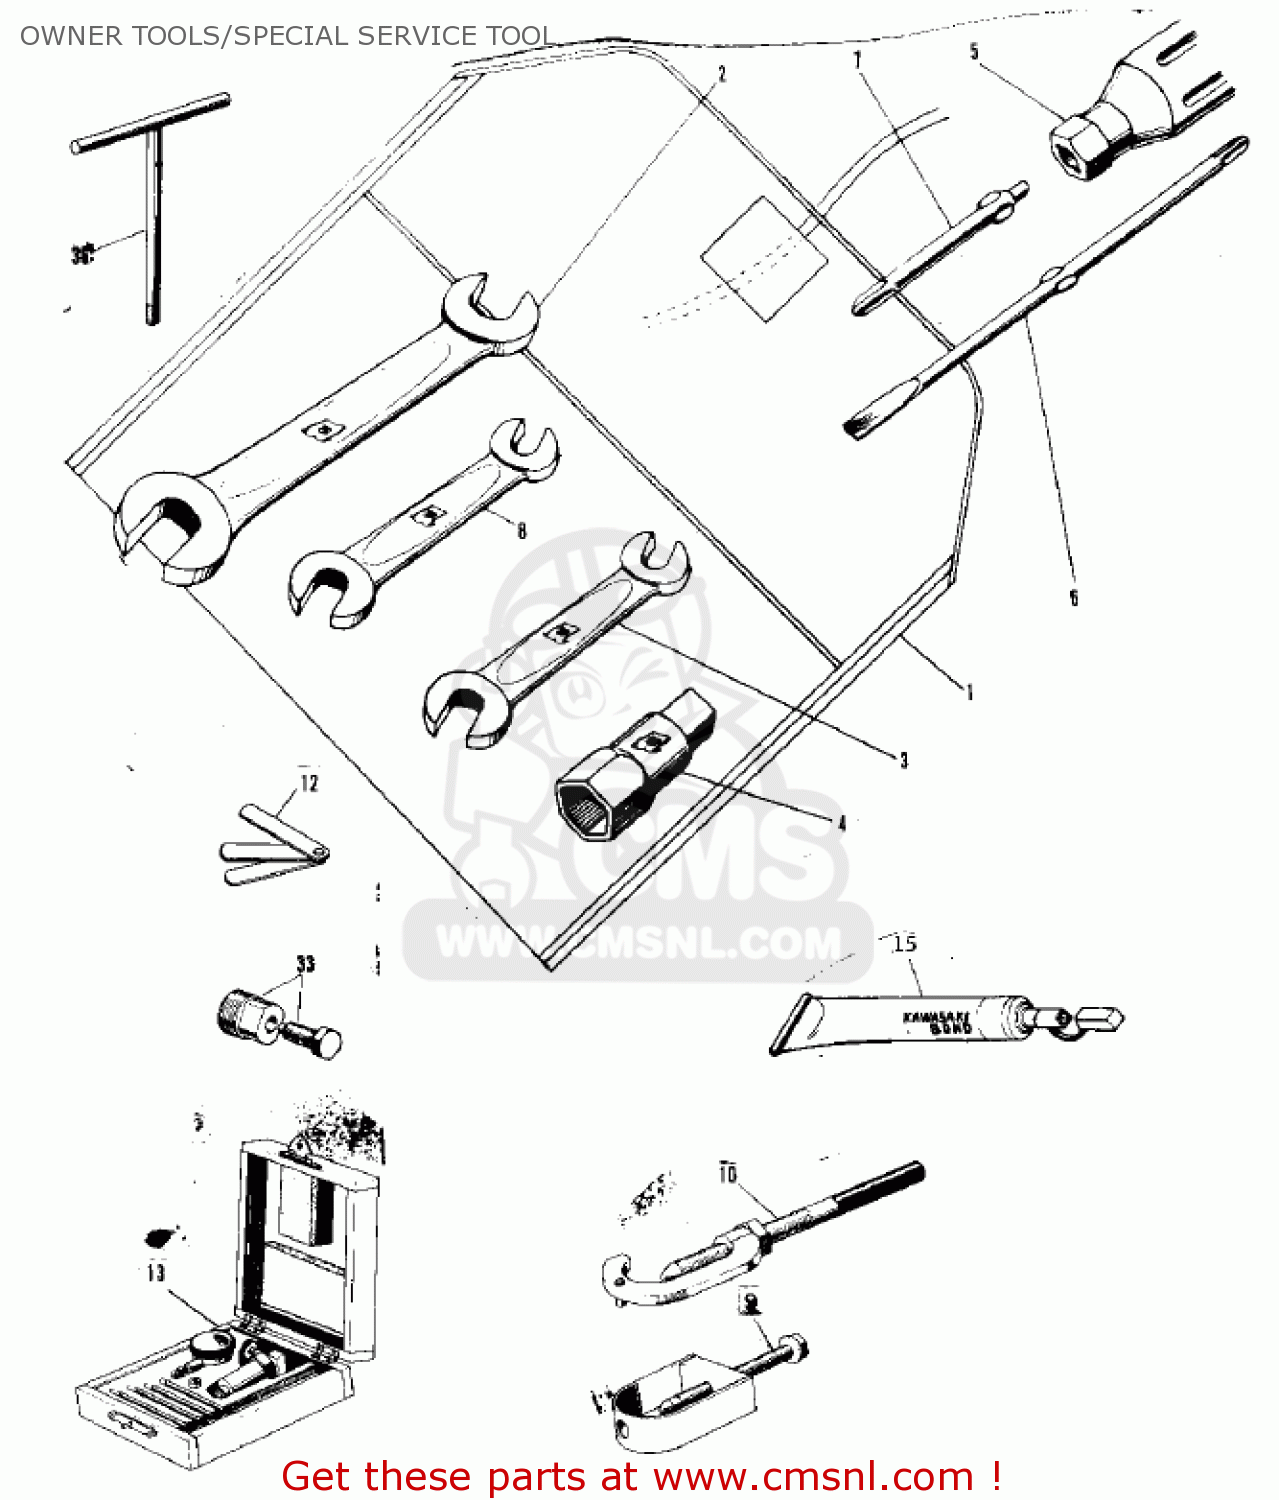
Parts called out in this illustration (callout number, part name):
1	BAG,TOOL
2	WRENCH-OPEN END,17X19
3	WRENCH-OPEN END,10X14
4	WRENCH-SPARK PLUG
5	SCREWDRIVER GRIP
6	TOOL-DRIVER
7	SCREW DRIVER-#3 PHLIP
8	WRENCH-OPEN END,10X13
15	LIQUID GASKET
?	TOOL KIT
